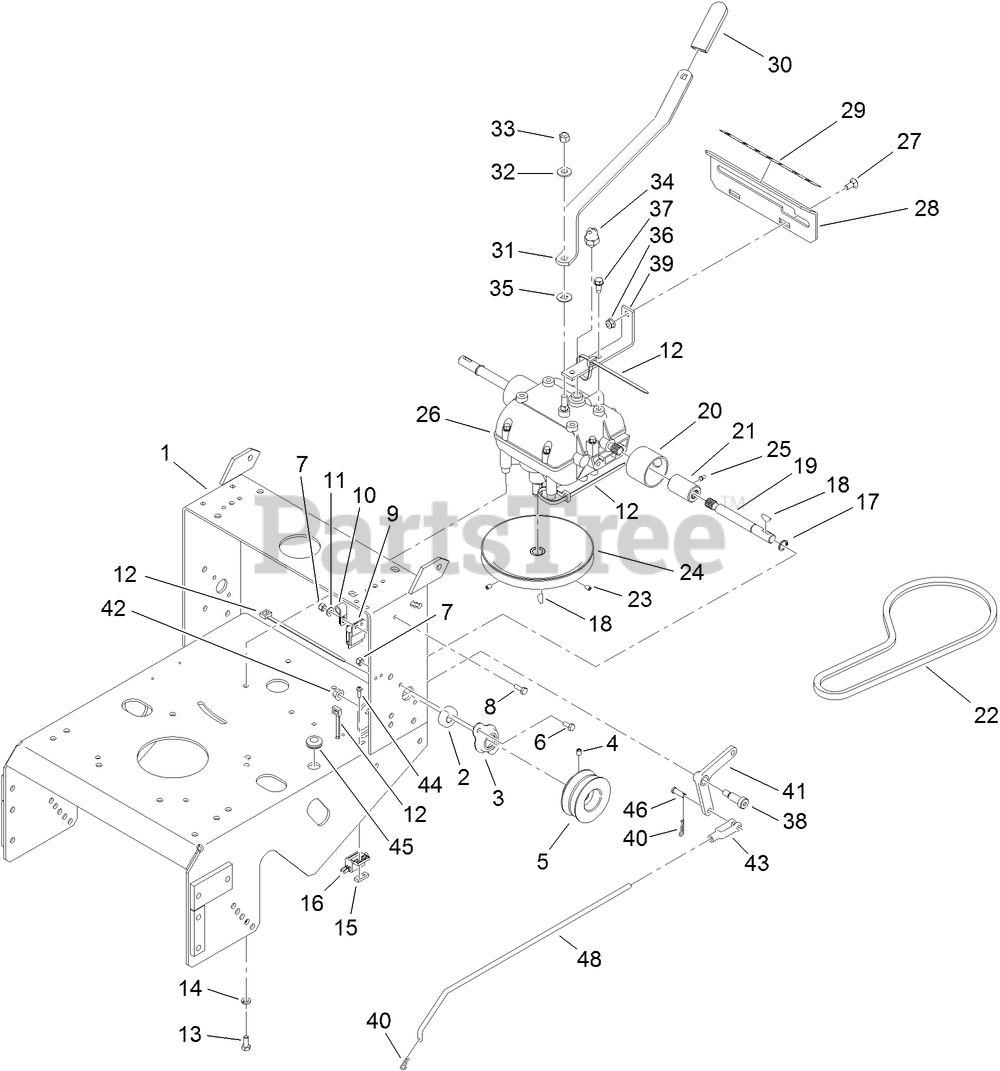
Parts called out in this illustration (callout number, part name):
1	FRAME-GEAR
2	BEARING-SHAFT
3	FLANGE-OUTPUT
4	SETSCREW
5	SHEAVE-TRANSMISSION
6	SCREW-HH
7	NUT-LOCK, NI
8	SCREW-HH
9	MODULE-INTERLOCK
10	CLIP-LOOM
11	WASHER-FLAT
12	TIE-PLASTIC
13	SCREW-HH
14	WASHER-LOCK
15	PLATE-TAPPED
16	SWITCH-OPEN, NORMALLY
17	RING-RETAINING
18	KEY-WOODRUFF
19	SHAFT-TRANSMISSION
20	GUARD-COUPLER
21	COUPLER
22	V-BELT
23	SCREW-HSH
24	SHEAVE-TRANSMISSION
25	FITTING-GREASE
26	TRANSMISSION
27	BOLT-CARR
28	PLATE-SHIFT
29	DECAL-SPEED, GROUND
30	GRIP-LEVER
31	LEVER-SHIFT
32	WASHER-BELLEVILLE
33	NUT-LOCK
34	Switch-Start, Neutral
35	WASHER
36	NUT-HF, NI
37	SCREW-HWH, THREAD CUT
38	BOLT-SHOULDER
39	BRACKET-PLATE, SHIFT
40	PIN-COTTER
41	BELLCRANK
42	NUT-HHF, WHIZ
43	YOKE-ADJUSTABLE
44	SCREW-PPH
45	GROMMET
46	PIN-CLEVIS
48	ARM-ASSIST, LINKAGE
